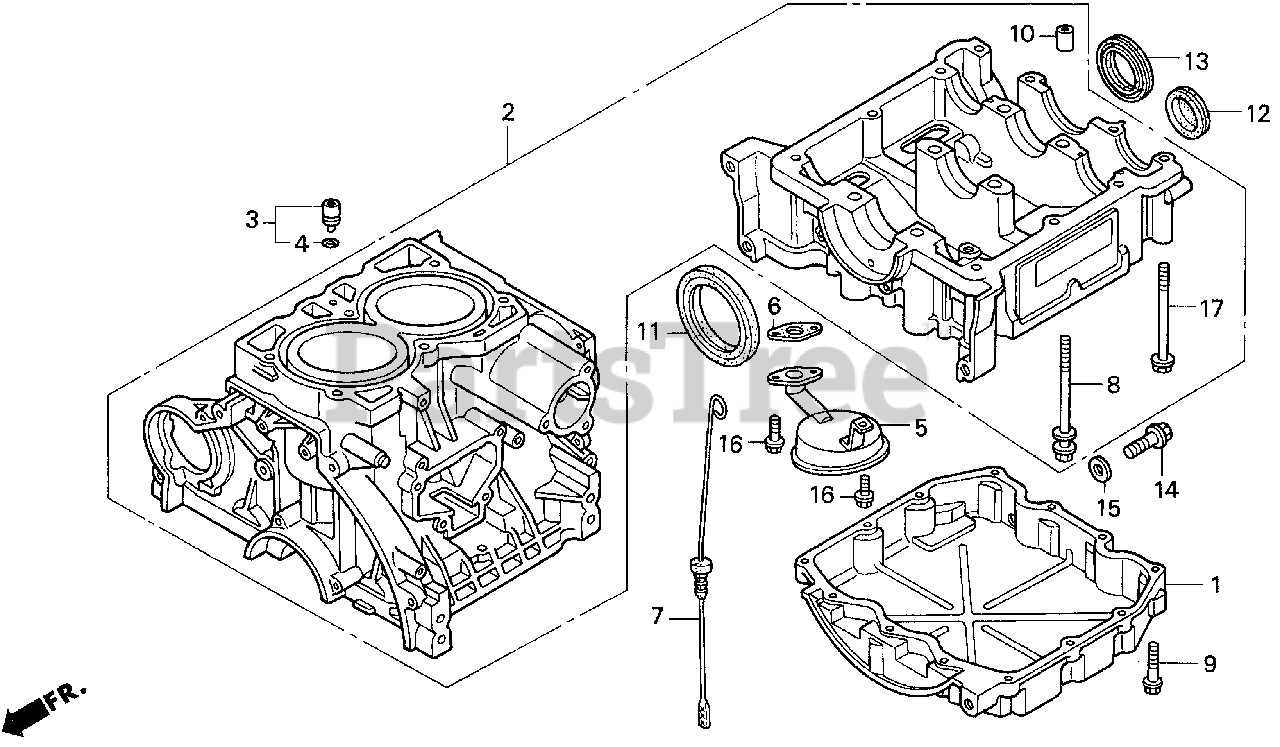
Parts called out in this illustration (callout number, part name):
2	BLOCK ASSY., CYLINDER
3	ORIFICE ASSY., OIL PASSAGE
4	O-RING (4.8X1.9)
5	STRAINER, OIL
6	GASKET, OIL STRAINER
7	DIPSTICK, OIL
8	BOLT-WASHER (10X105)
9	BOLT, FLANGE (6X28)
10	PIN, DOWEL (13X20)
11	OIL SEAL (65X88X12)
12	PLUG, SEALING (42X7)
13	OIL SEAL (35X50X8)
14	BOLT, DRAIN PLUG (12MM)
15	WASHER, DRAIN PLUG (12MM)
16	BOLT, FLANGE (6X18)
17	BOLT, FLANGE (8X85)
